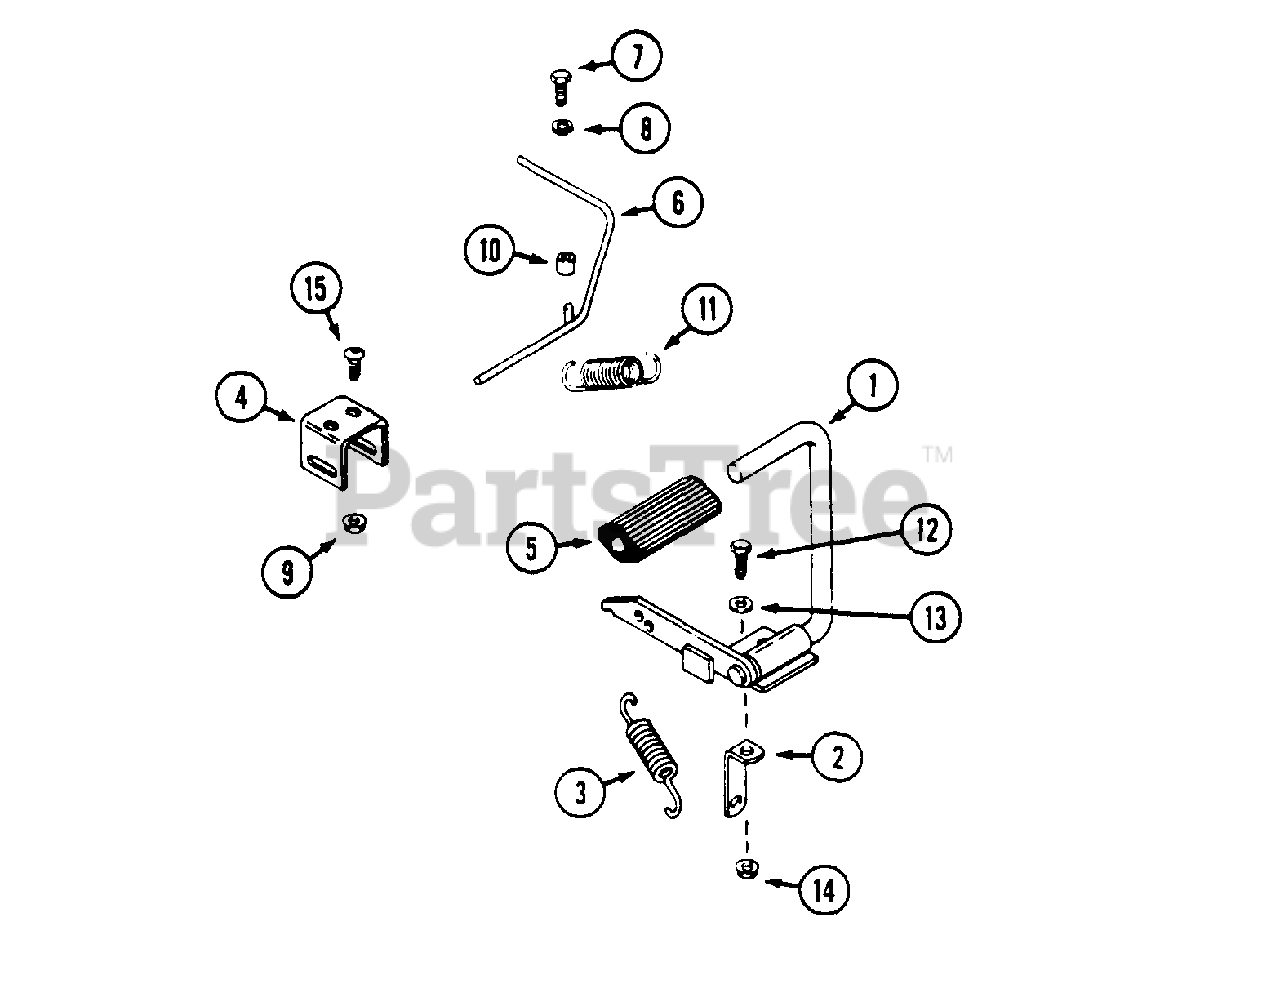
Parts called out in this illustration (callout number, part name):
1	PEDAL - parking brake
2	TAB - spring mount
3	SPRING - brake return
4	BRACKET - brack lock
5	PAD - brake pedal
6	LEVER - brake lock
7	SCREW - 5/16" - 18 x 5/8" allen head
8	LOCKWASHER - 5/16"
9	NUT - 1/4" - 20 flange lock
11	SPRING - return, lock lever
12	BOLT - 5/16" - 18 x 1"
13	WASHER - 5/16"
14	NUT - 5/16" - 18 flange lock
15	SCREW - 1/4" - 20 x 1/2" allen head
